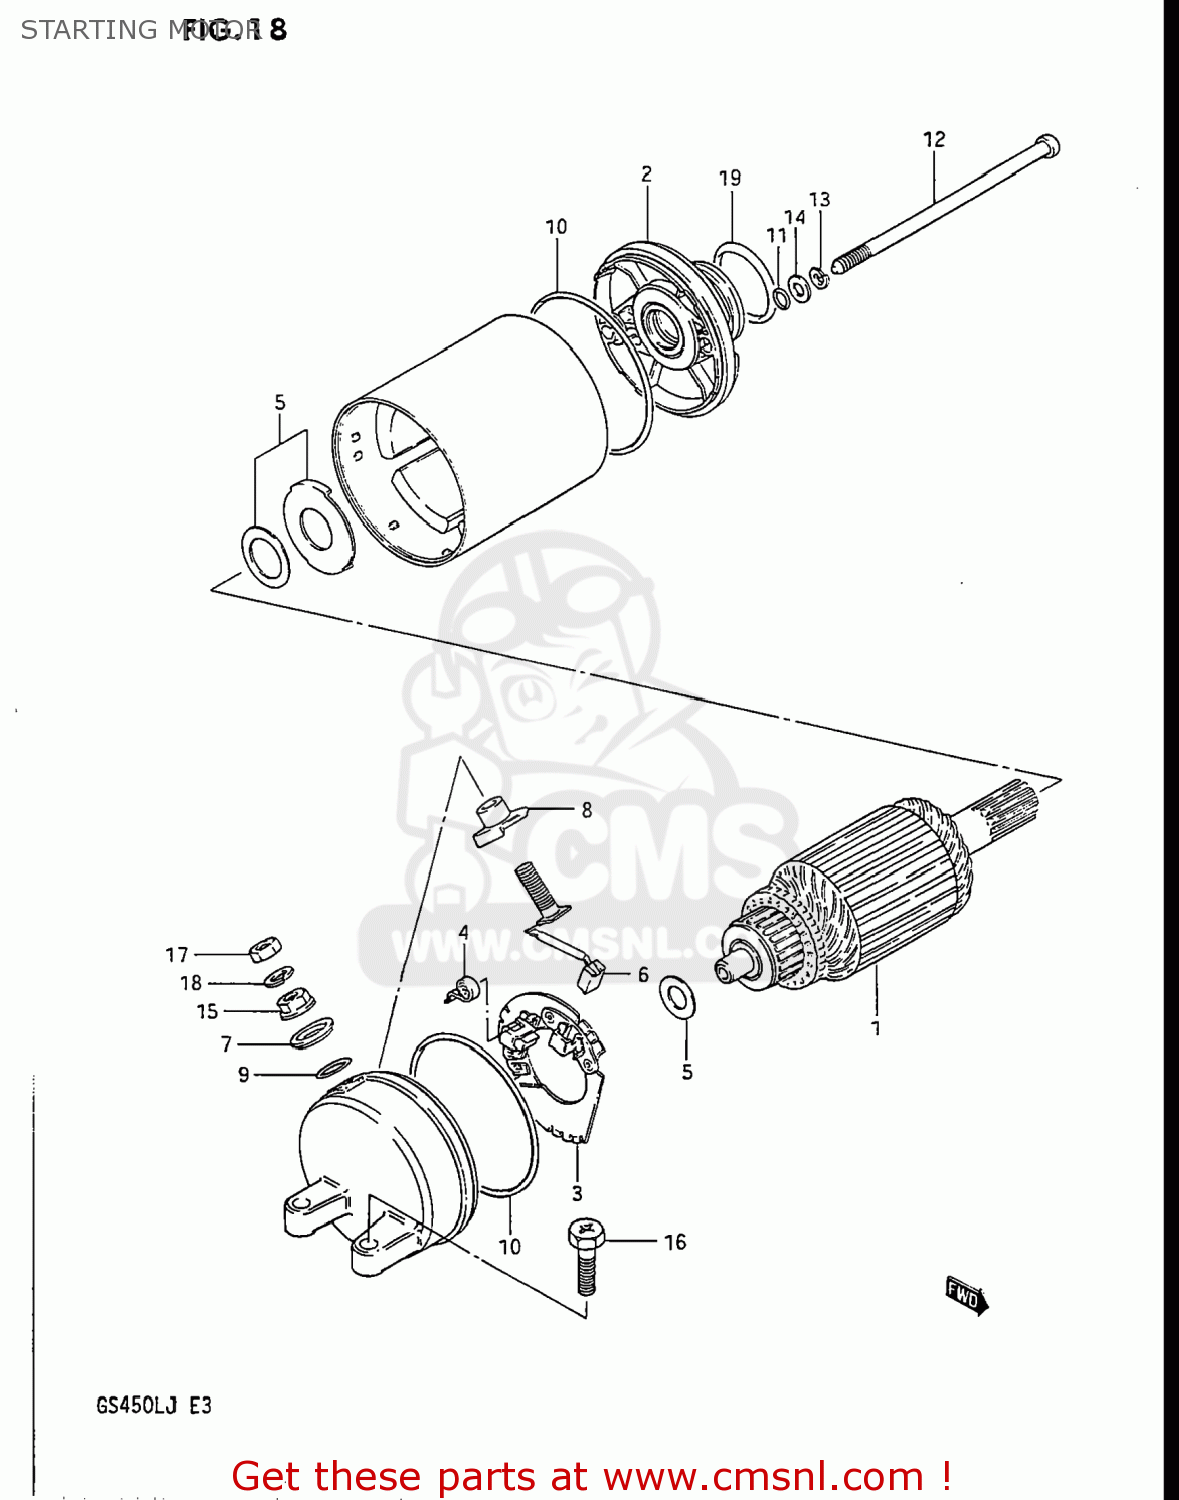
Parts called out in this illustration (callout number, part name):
1	ARMATURE
2	BRACKET SET,STARTING MOTOR
3	HOLDER,BRUSH
4	SPRING
5	SHIM SET,STARTING MOTOR
6	BRUSH SUB ASSY,STARTING MOTOR
7	BUSHING
8	BUSH,B
9	O RING
10	O RING
11	O RING
12	BOLT
13	LOCK WASHER
14	WASHER
15	NUT
16	SCREW (6X25)
17	NUT
18	WASHER,LOCK
19	O RING(D:3,ID:24.5)
